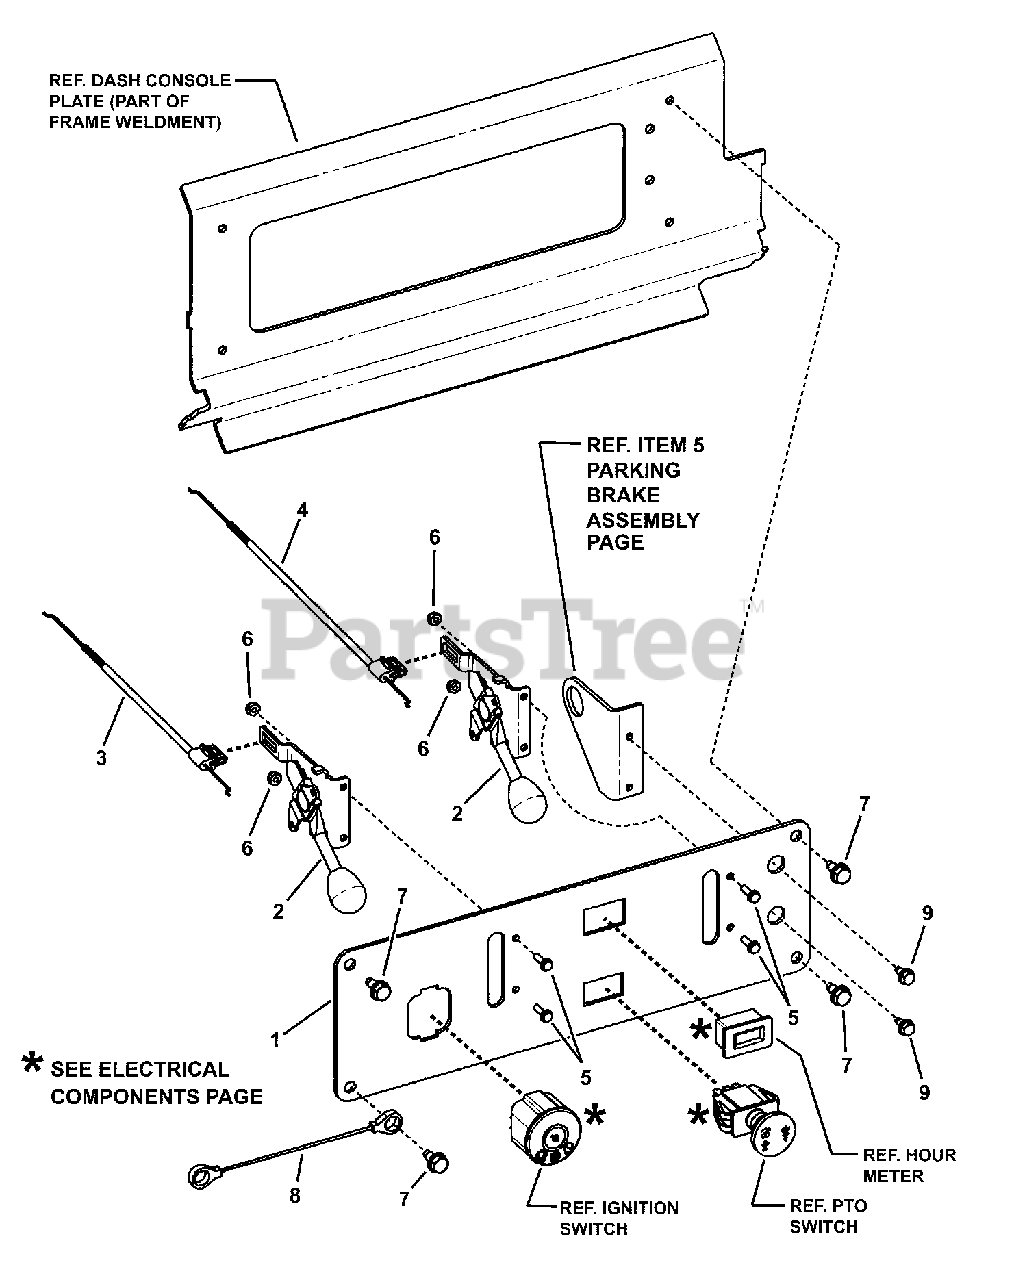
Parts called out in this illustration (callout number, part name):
1	DASH CONSOLE, Black
2	CONTROL LEVER, Throttle/Choke
3	CONTROL CABLE, Throttle (53.99" long)
4	CHOKE CABLE, Briggs, HZT (58.49" long)
4	CONTROL CABLE, Choke (Kawasaki)(53.49" long)
5	SCREW, #10-32 x 5/8" Hex Washer Self-Tap
6	NUT, #10-32 Hex Nyloc
7	SCREW, 5/16-18 x 5/8" Hex Washer Self-Tap
8	TETHER STRAP
9	SCREW, 1/4-20 x 1/2" Hex Washer Self-Tap
